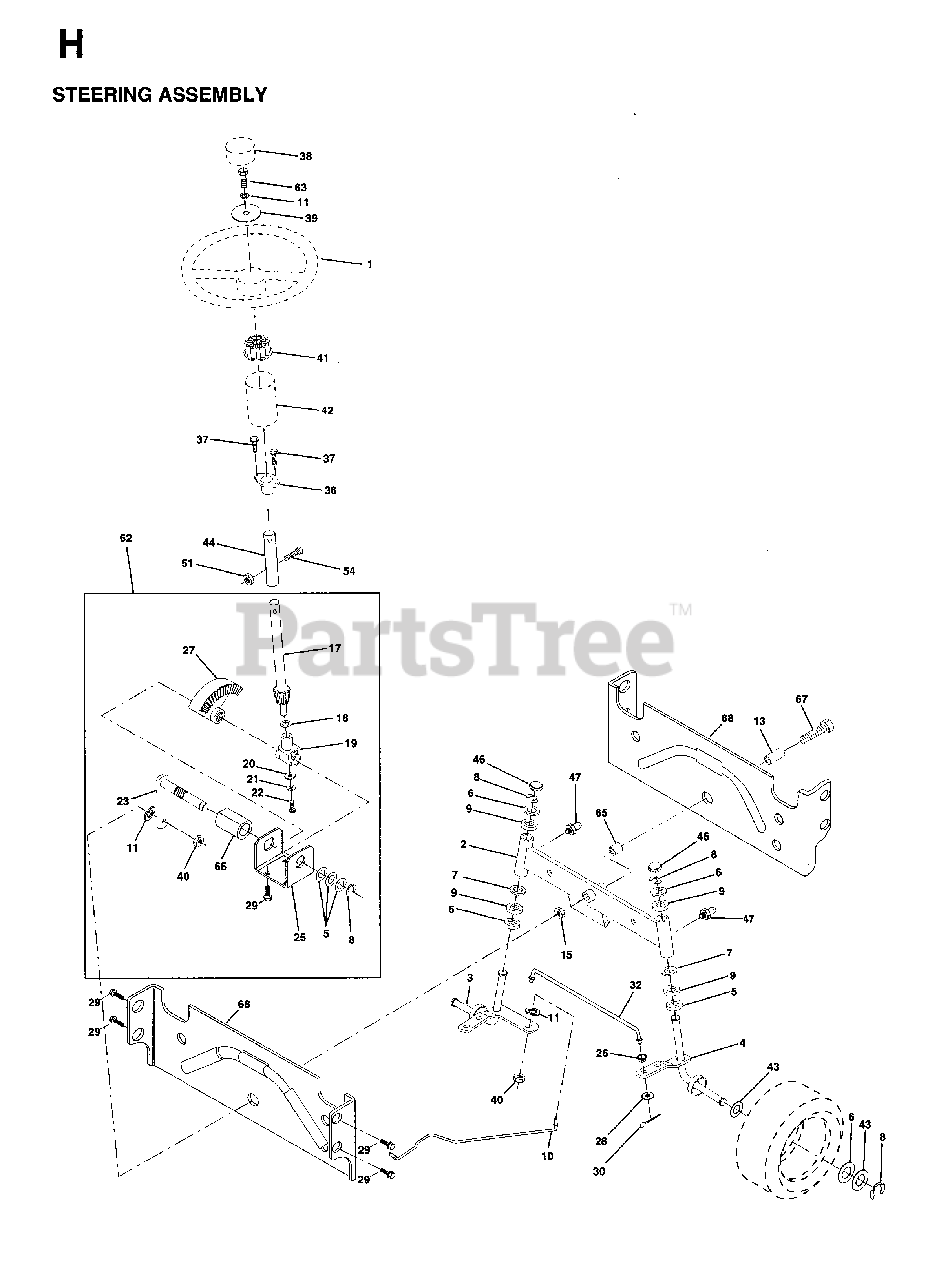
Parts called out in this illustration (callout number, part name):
2	AXLE ASSY
3	SPINDLE.ASM.LH
4	SPINDLE ASM, RH
8	RING CLIP
9	BRNG T
10	DRAGLINK-STAMPED
11	WASHER, LOCK 3/8
13	BEARING AXLE
15	NUT-LOC,FLANGE LT
17	SHAFT ASM STEERING
18	THRUST WASHER
19	SHAFT,SUPPORT
20	WASHER
21	LOCKWASHER
22	SCREW
23	PITMAN SHAFT ASSY
25	BRACKET STEERING
26	BUSHING.DRAGLINK
27	GEAR.SECTOR
28	WASHER
29	SCREW
30	COTTER PIN
32	TIE ROD
36	BUSHING, STEERING
38	RP INSERT
39	WASHER T
40	GRIPCO NUT
41	ADAPTER LT
42	STEERING BOOT, GRAY
44	EXT SHAFT STEERING
46	CAP.SPINDLE
47	ZERK M
51	NUT.71038.31-18.HEX.NYLOCK
54	BOLT.5/16-18X1-1/4 FULL.THREAD
62	KIT, STEERING ASSEMBLY
65	SPACER AXLE
66	BEARING ARM
67	BOLT.HEX.FINISHED.5/8
